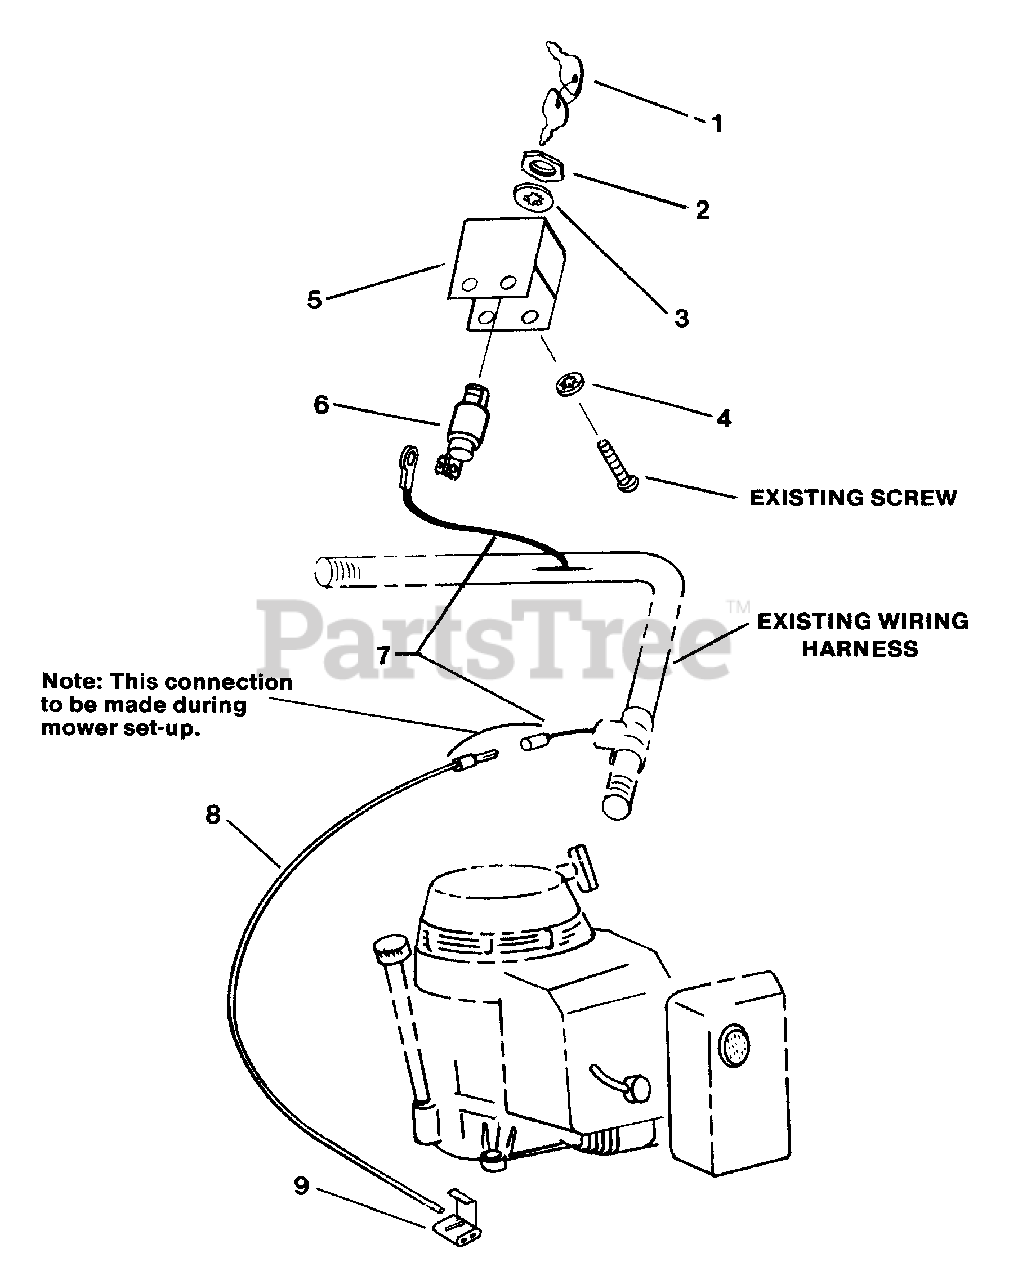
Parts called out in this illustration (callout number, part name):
1	Set of 2 Keys
2	5/8"-32 Hex Nut
3	5/8" Internal Tooth Lock Washer
4	#10 Internal Tooth Lock Washer
5	Bracket w/Decal
6	Keyswitch
7	Kill Wire (Red)
8	Engine Wire (Red)
